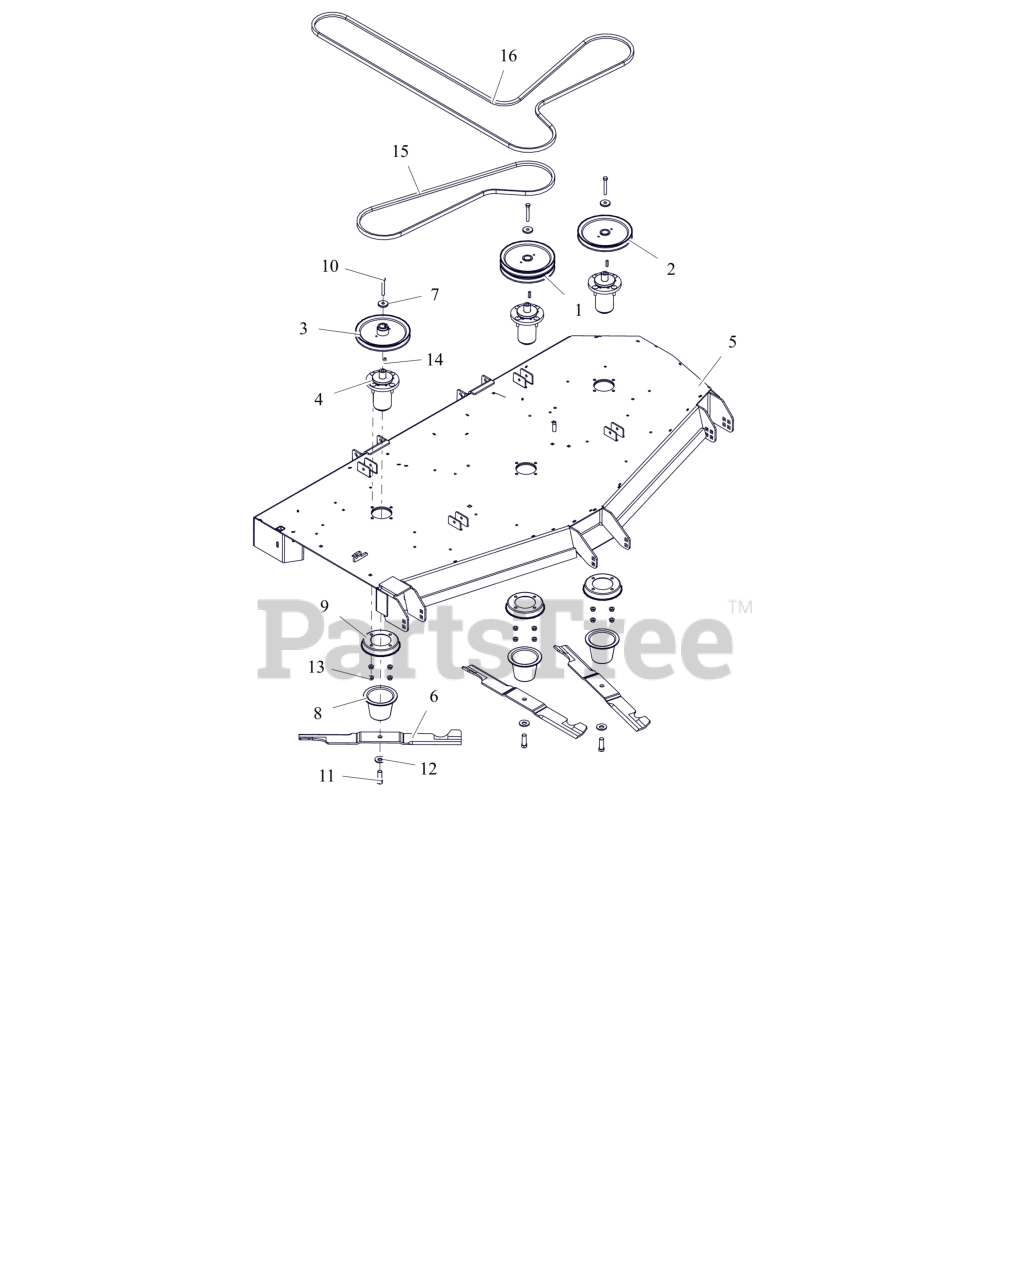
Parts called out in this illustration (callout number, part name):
1	SHEAVE-DOUBLE 1.00"ID X 8.25"OD
2	SHEAVE, SINGLE 1.00" X 8.25" OD
3	SHEAVE, SINGLE 1.00" ID X 8.25" OD
4	ASM, MAINT FREE ALUM SPINDLE
5	WLDMT, 72" SIDE DISCH DECK-X3 (RED) W/ SAFETY DECALS
6	BLADE, 72"
7	RETAINER, SHEAVE
8	GUARD, SPINDLE LOWER
9	GUARD, SPINDLE TOP
10	BLT, HEX .38-16X2.75 G8 ZCC
11	BLT, HEX .62-18X1.75 G8 ZCC
12	WSHR-BLVL .669X1.535X.138
13	NUT-LK-CTR-FLG .375-16 GF ZCC
14	KEY, SQ .25X.25X1.00 RC 40-50
15	V-BELT, B-COGGED
16	V-BELT, B SECTION
